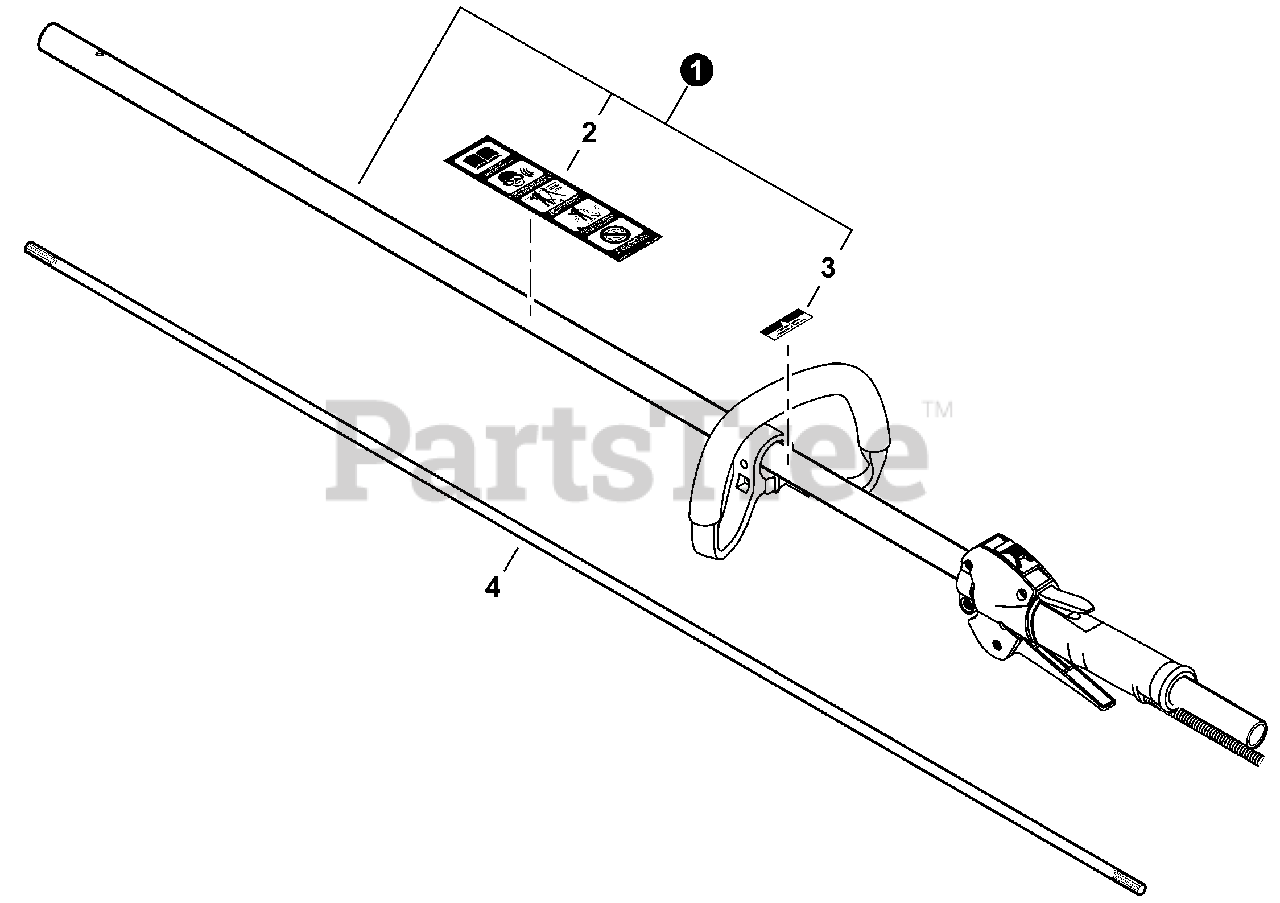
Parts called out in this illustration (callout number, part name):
1	MAIN PIPE ASSY
2	LABEL - CAUTION
3	LABEL - HANDLE
4	MAINSHAFT
